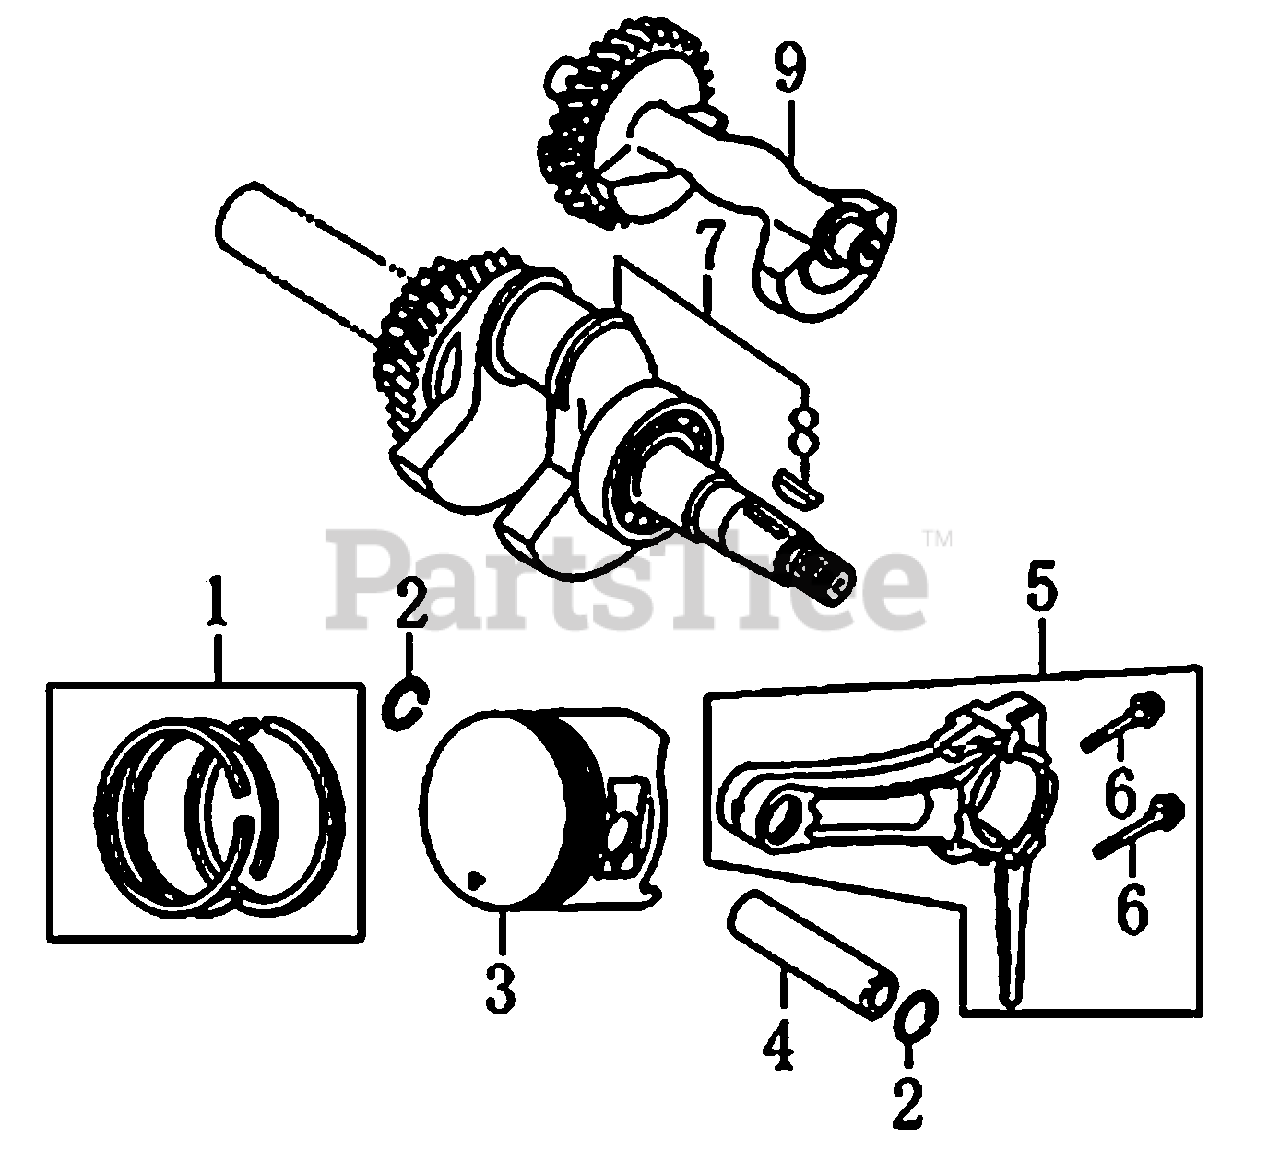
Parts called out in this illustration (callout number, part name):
1	RING SET, PISTON
2	CLIP, PISTON PIN
4	PIN, PISTON
5	CONNECTING ROD ASSY
6	BOLT, CONNECTING ROD
7	CRANKSHAFT ASSY
8	KEY, SPECIAL WOODRUFF
9	WEIGHT, BALANCER
